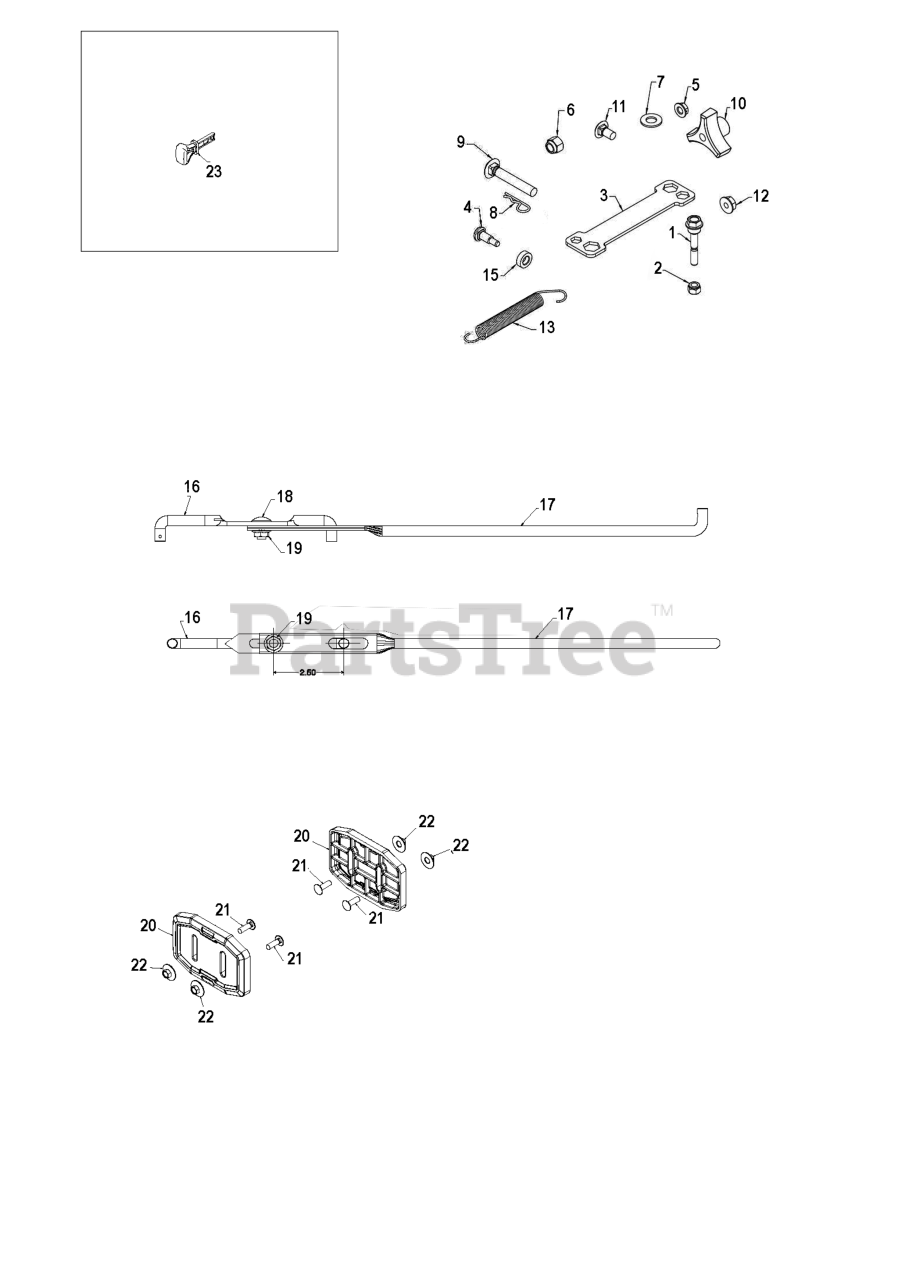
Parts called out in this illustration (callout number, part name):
1	BOLT.1/4-20 X 1-13/16 SHEAR
2	LOCKNUT.NYLOC.1/4-20
3	WRENCH.SNOWTHROWER.ZINC.YZ
4	BOLT, SHOULDER
4	BOLT.CARR.W.3125 SHLDR..25-20
5	NUT.HEX.FLANGE.1/4
6	NUT
7	WASHER
8	SPRING RETAINER
9	BOLT 3/8-16 X 2-1/4
10	KNOB.HANDLE.3/8.TRI-POINT.BLAC
11	BOLT CAR BLK 5/16-18 X 5/8
12	NUT.LOCK.5/16-18
12	LOCKNUT-FLANGE 5/16-18
13	SPRING.DEFLECTOR.REM.CHUTE
15	WASHER.NYLON.326 X.625 X.205
16	ROD.SHIFTER.TOP.HYD
17	ROD, LOWER, SPEED CONTROL
18	BOLT
19	NUT.FLANGE.5/16
20	PLATE.SKID.SHOE.COMPOSITE
21	BOLT.CARR.5/16-18X1.BLACK
22	NUT.HEX.FL 5/16-18 TOP LCK BLK
23	KEY SET(2 KEYS) SKSN0407.1
